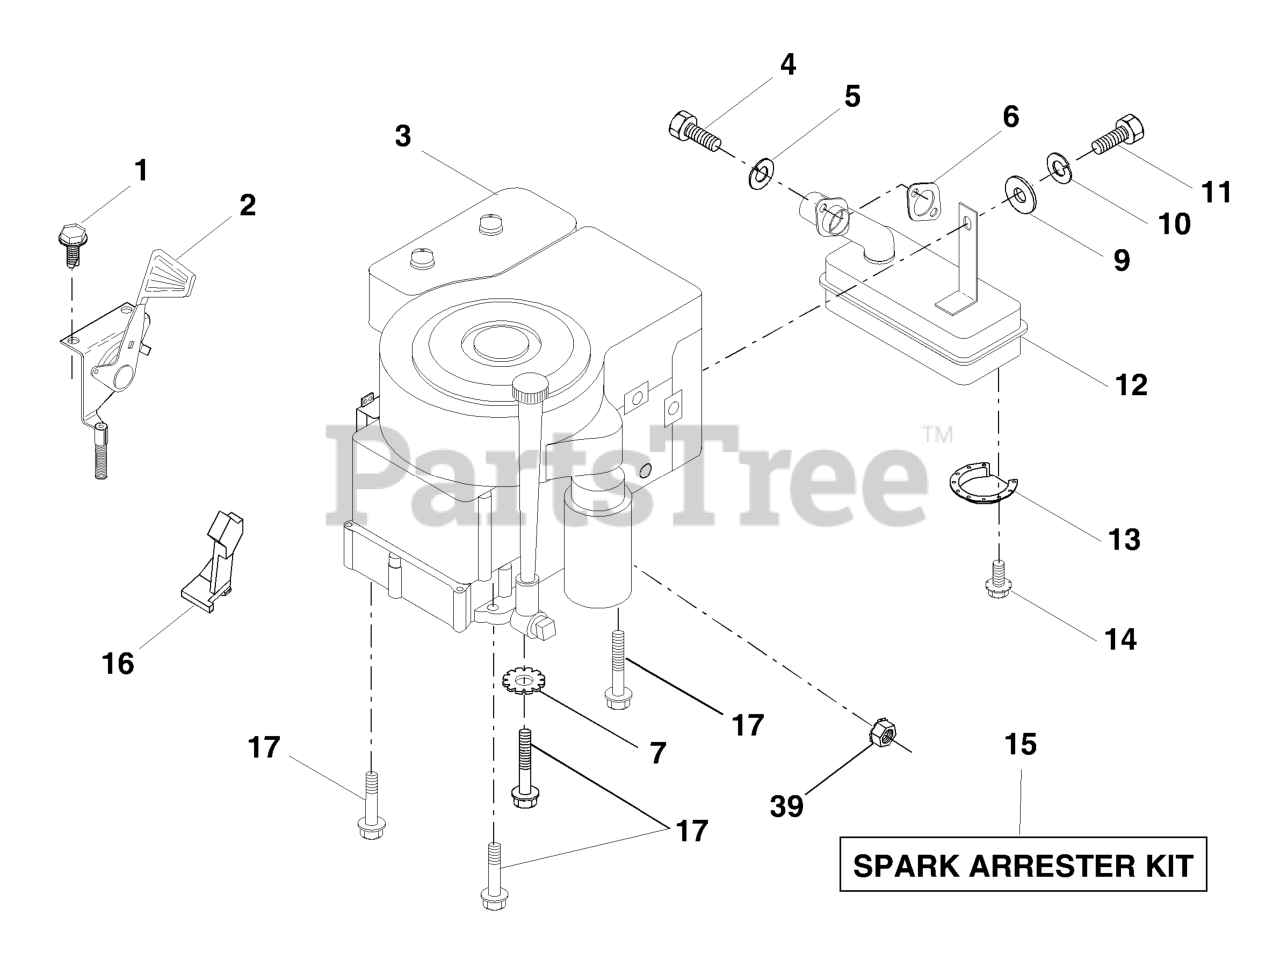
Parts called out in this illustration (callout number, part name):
2	CONTROL.TH/CH.RH.BLK.FLG.EEC
4	SCREW
5	WASHER.LOCK.HVY.HLCL.SPR.5/16
6	GASKET.ENG.1.313 ID.TIN PLATED
7	LOCKWASHER
9	WASHER
10	LOCKWASHER
11	Bolt, Hex Fin.
12	MUFFLER.SINGLE.B&S.12HP
13	DEFL MUFFLER LTV
14	SCREW
15	KIT.SPARK ARRESTOR 794945 B&S
16	STOP THROTTLE
17	SCREW LT
39	NUT FLANGE 1/4-20 STARTER NUT
